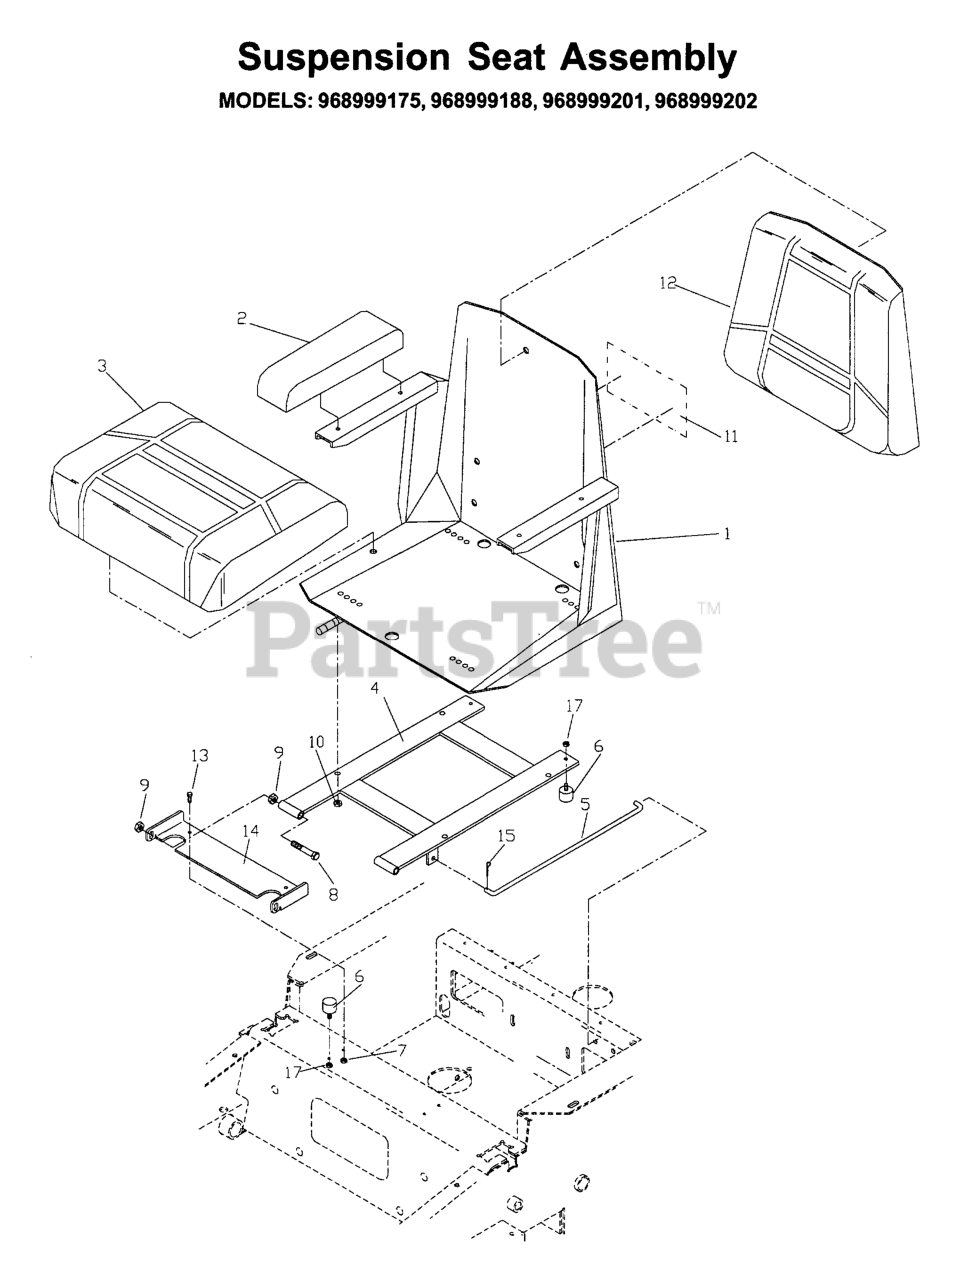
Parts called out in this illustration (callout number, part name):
1	SEAT, COMPLETE
2	ARM REST CUSHION
3	SEAT CUSHION
4	SEAT MOUNT
6	STUD/PLATE MOUNT
7	NUT 1/4C CENTERLOCK
8	HCS 3/8C X 3
9	NUT 3/8C CENTERBLOCK
10	NUT M8-1.25HX NYL RNGGR8.8
11	DECAL, CROWN H
12	BACK CUSHION
13	HCS 1/4C X 3/4 HCS
14	SEAT BRKT W/DECAL
15	RP_COTTER PIN 1/8 X 3/4
16	SEAT RAILS
17	NUT.1/4-20.HEX.NYLOC.ZD
18	SEAT HARNESS
19	SEAT SWITCH
